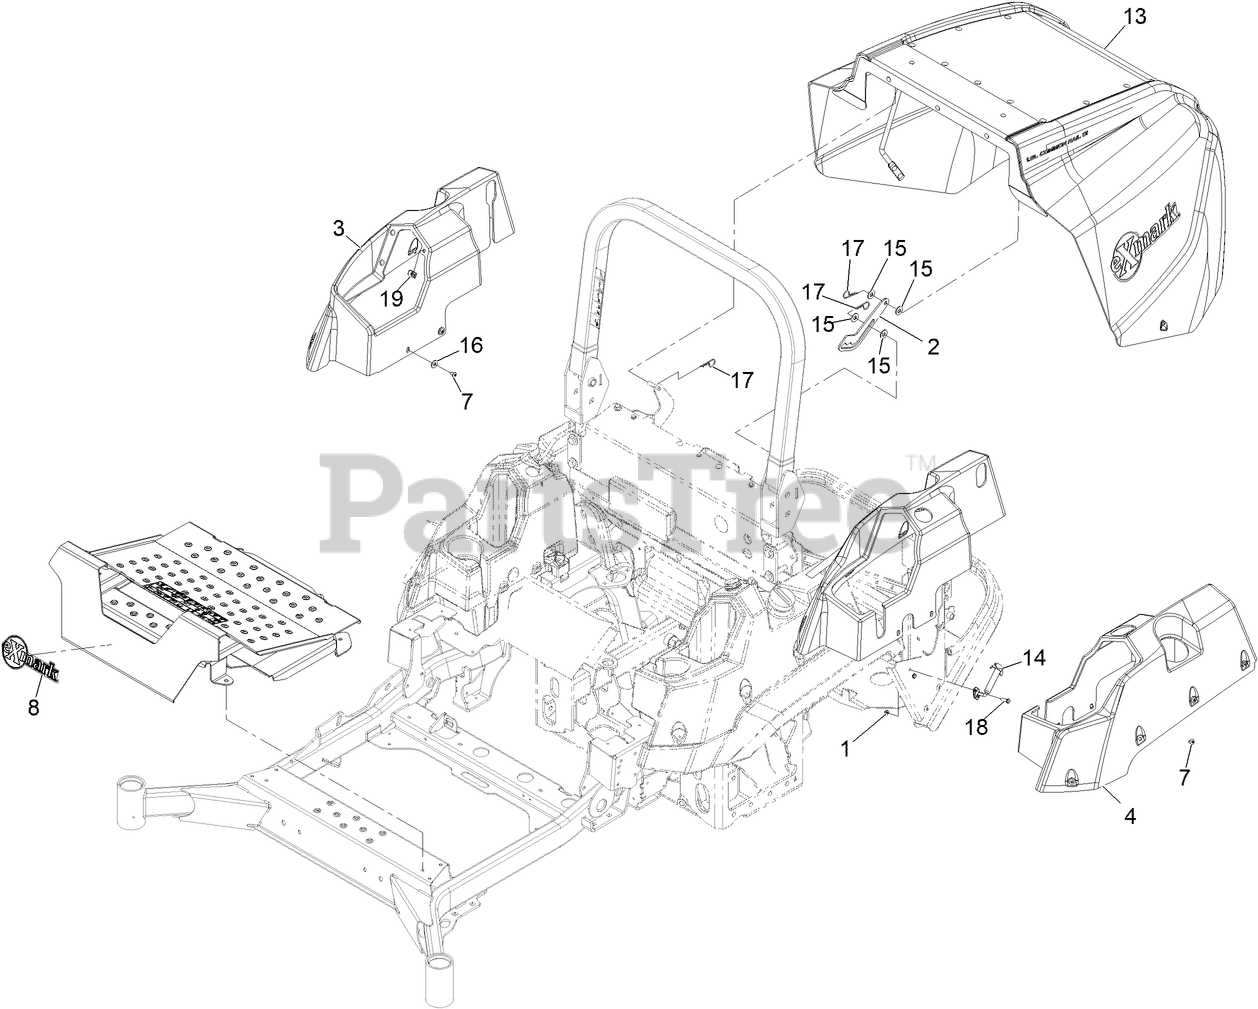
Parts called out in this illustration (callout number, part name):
2	PROP-HOOD
3	COVER-TANK, RH
4	COVER-TANK, LH
7	SCREW-TORX
8	DECAL-EXMARK
13	ASM, HOOD LZSD
14	LATCH-HOOK
15	WASHER-FLAT
16	WASHER-FLAT
17	PIN-COTTER, HAIR
18	SCREW-HWH
